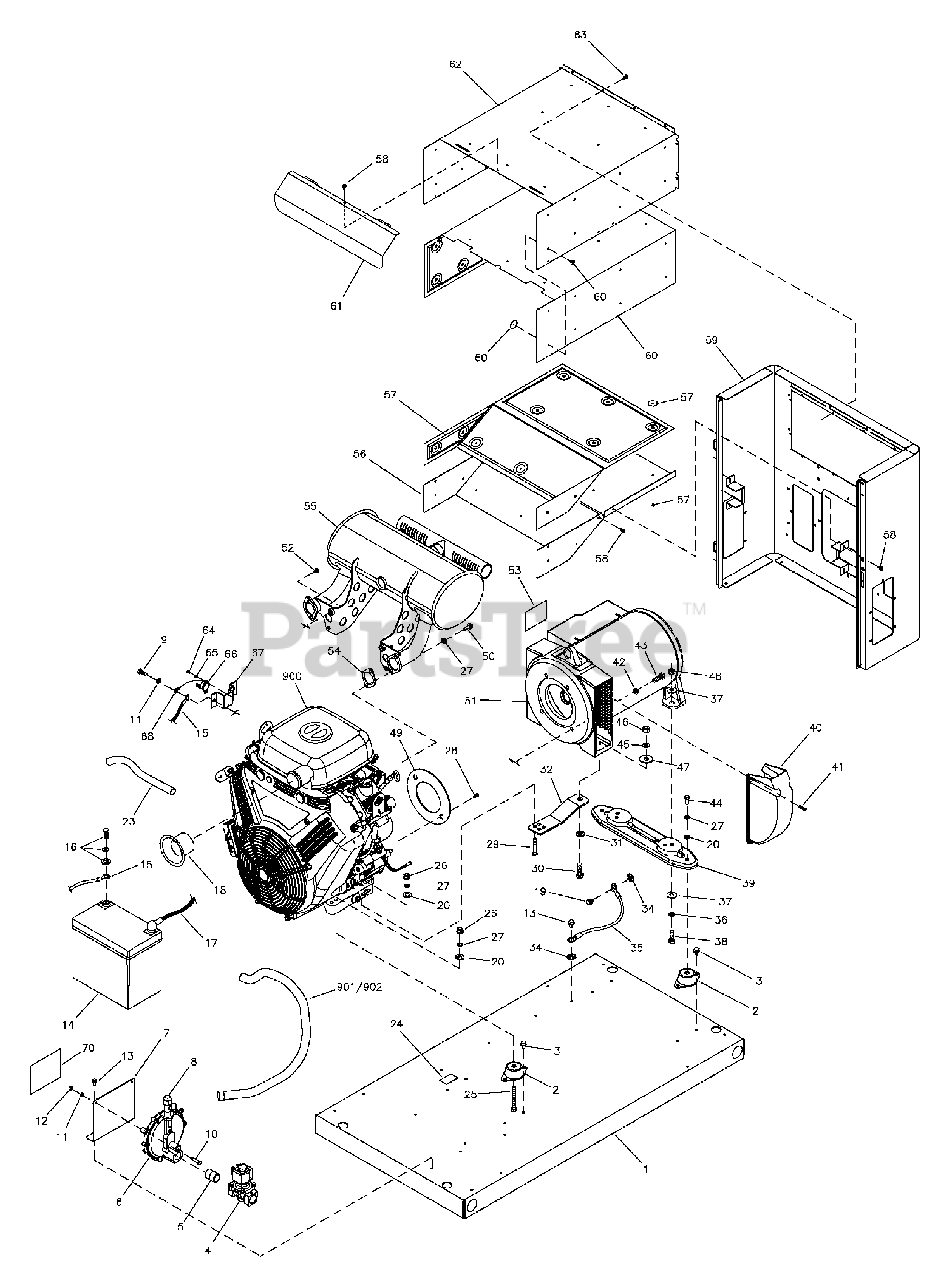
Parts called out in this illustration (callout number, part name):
2	MOUNT, Vibration
4	SOLENOID, Gas Fuel
6	REGULATOR, NG/LPG
7	BRACKET
9	* CAPSCREW, Hex, Head, M6-1 x 16
10	* CAPSCREW, Hex, Head, M6-1 x 30
11	* WASHER, Lock, 1/4
12	* NUT, M6-1
13	BOLT
16	KIT, Hardware, Battery
19	* CAPSCREW, Hex, Head, M6-1 x 12
20	* WASHER, Flat, 5/16-M8
23	HOSE, Oil Drain
24	DECAL
25	* CAPSCREW, Hex, Head, 5/16-18 x 2.5
26	* NUT, 5/16-18
27	* WASHER, Lock, 5/16-M8
28	* CAPSCREW, Hex, Head, 5/16-24 x 3/4
29	* CAPSCREW, Hex, Head, 5/16-18 x 2
30	* CAPSCREW, Hex, Head, M12-1.75 x 35
31	* WASHER, M12
34	* WASHER, Shakeproof, M6-1/4
36	* WASHER, Lock, M10
37	* WASHER, Flat, M10
38	* CAPSCREW, Hex, Head, M10-1.5 x 30
39	SUPPORT, Alternator
41	* SCREW, Phillips Head, M5-0.8 x 20
42	* WASHER, Lock, 3/8
43	* CAPSCREW, Socket Head, 3/8-16 x 1-1/4
44	* CAPSCREW, Hex, Head, 5/16-18 x 3/4
45	* WASHER, Lock, M12
46	* NUT, Hex, M12
47	* WASHER, Flat, M12
48	* NUT, M10
50	SCREW
51	ALTERNATOR, Complete
53	DECAL
59	BULKHEAD, Alternator
62	BOX, Muffler Top
64	* SCREW, Phillips Head, 4-40 x 0.19
65	* WASHER, Lock, #4
66	SWITCH, Temp
67	PLATE, Temp Switch
900	** ENGINE
